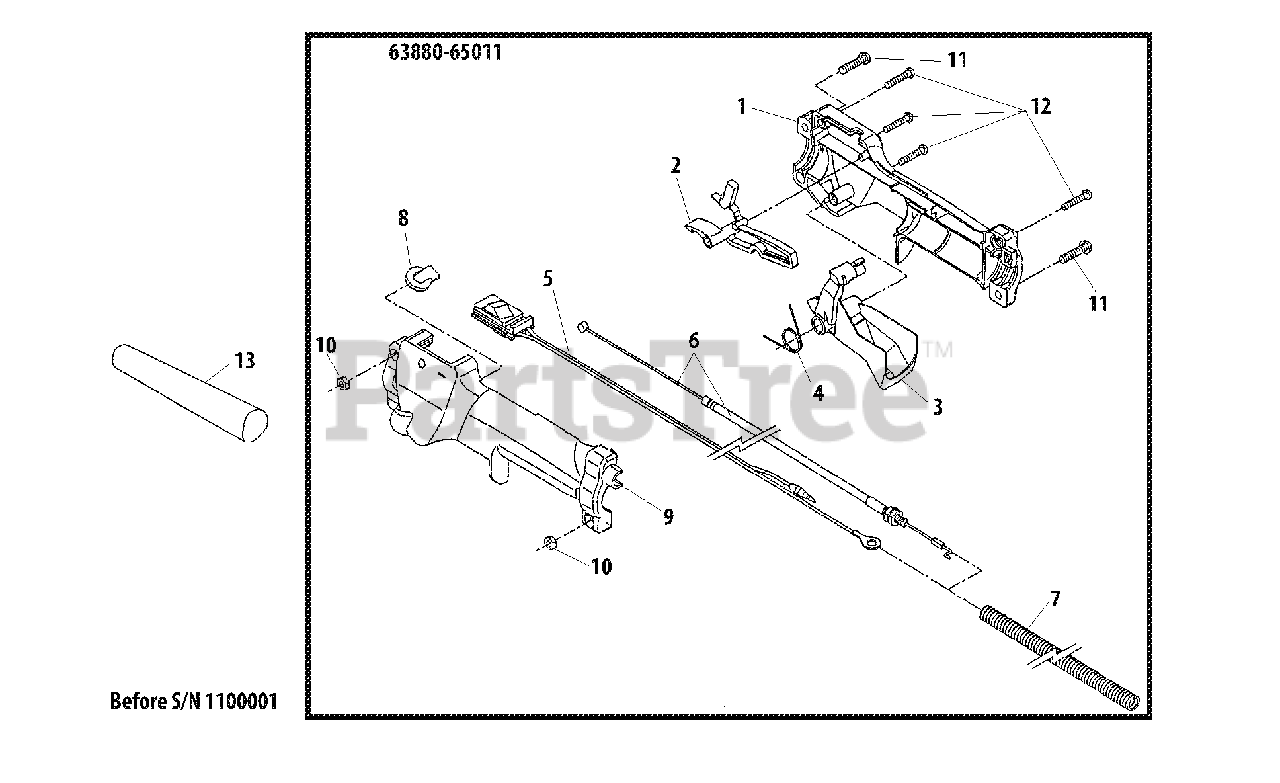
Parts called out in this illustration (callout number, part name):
1	CONTROL HANDLE - RIGHT
2	LEVER, THROTTLE LOCKOUT
3	TRIGGER, THROTTLE
4	SPRING, THROTTLE RETURN
5	SWITCH, ON-OFF
6	CABLE, THROTTLE
7	TUBE, PLASTIC PROTECTIVE
8	PLUG
9	CONTROL HANDLE - LEFT
10	NUT M5
11	SCREW M5×20
12	SCREW, TAPPING M4×20
13	COLLAR
63880-65011	THROTTLE CONTROL ASSY
